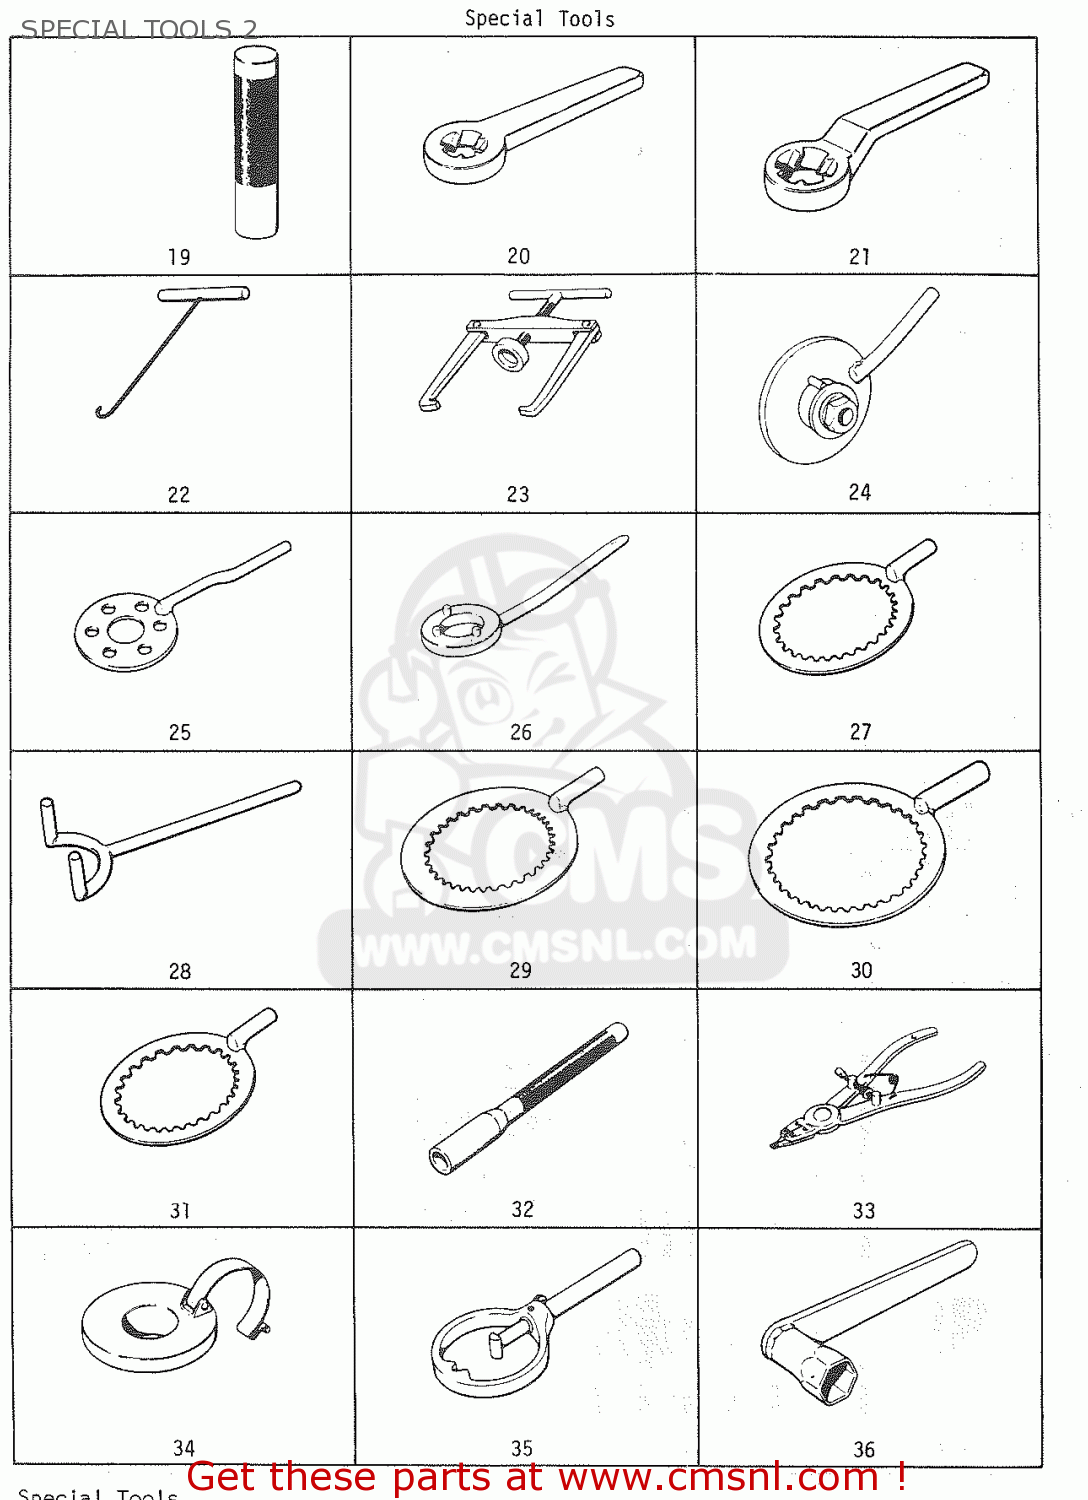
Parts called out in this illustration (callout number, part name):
33	SNAP RING OPENER
35	ENGINE SPROCKET HOLDER
36	SPARK PLUG WRENCH
